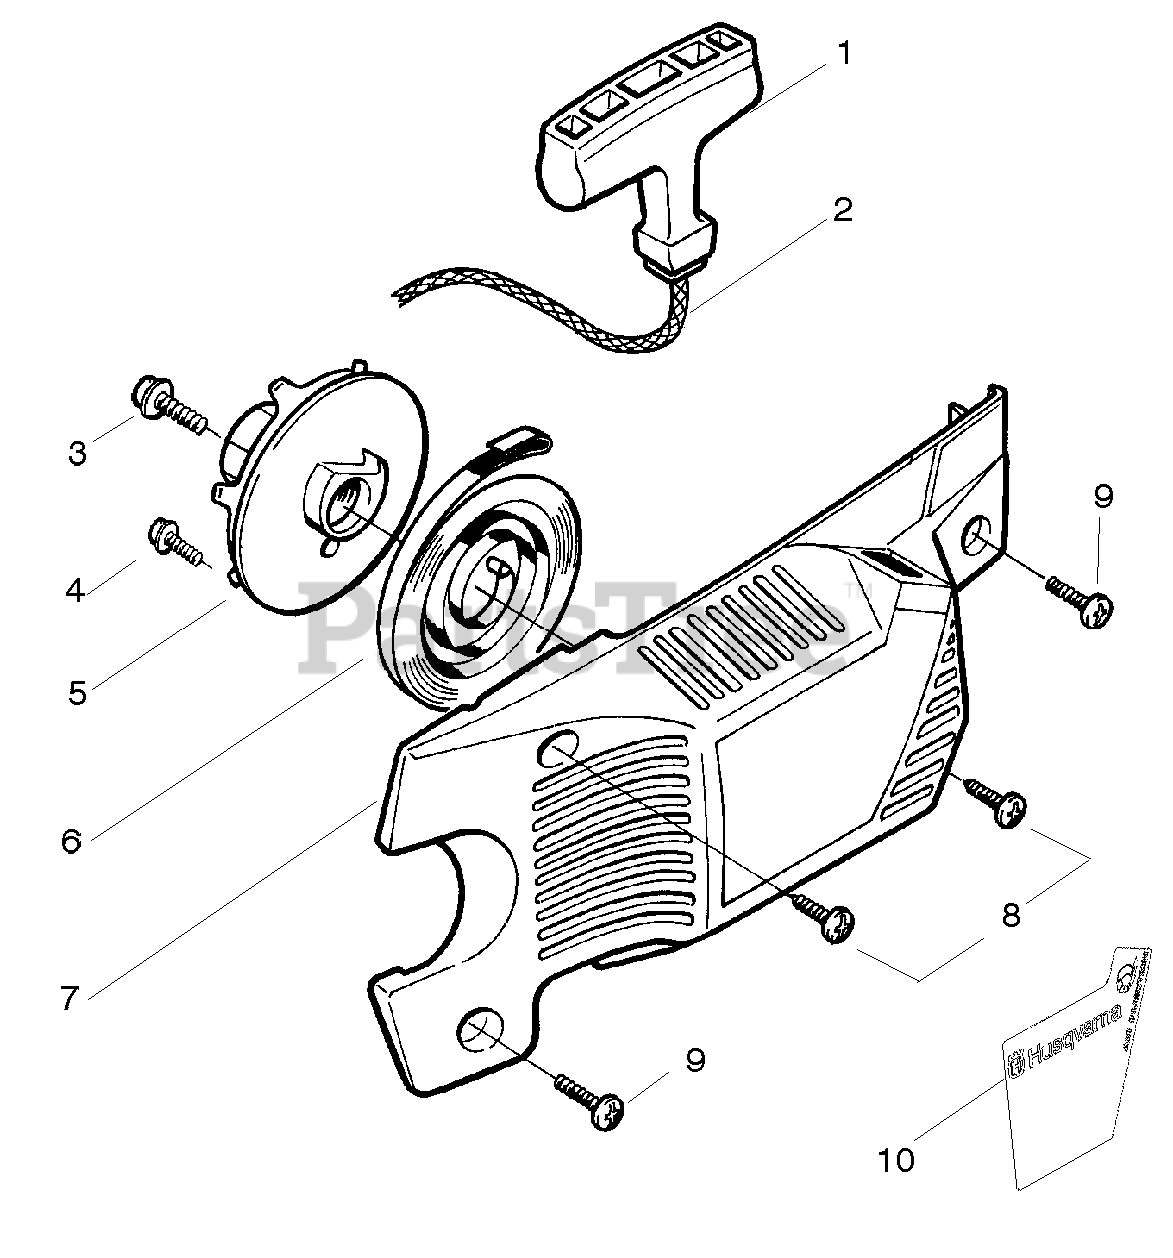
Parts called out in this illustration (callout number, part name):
1	STARTER HANDLE
5	PULLEY 36/41
6	RETURN SPRING
7	FAN HOUSING ASSEMBLY
8	SCREW,STRTR CVR 36/41
10	Decal-Fan Housing
